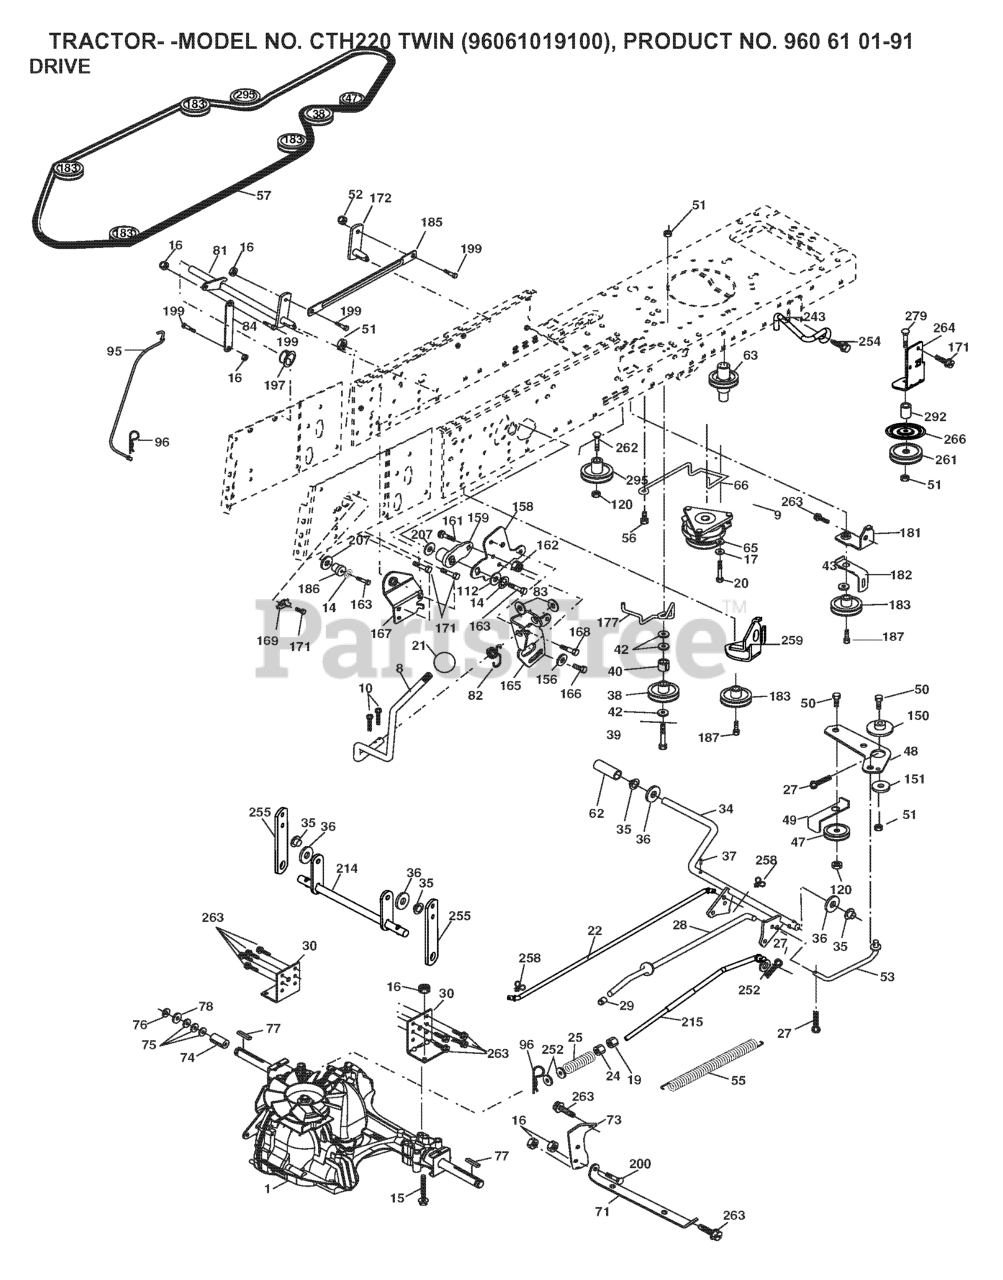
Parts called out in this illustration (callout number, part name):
8	ROD SHIFT FENDER ADJUST LT
9	CLUTCH.ELECTRIC.OGURA.EURO.
10	PIN COTTER
14	LOCKWASHER
15	BOLT HEX 5/16-18 GR 5
16	NUT.71038.31-18.HEX.NYLOCK
19	NUT
20	BOLT HEX 7/16-20X4-1/4"
21	KNOB.DUCKHEAD.1/2
22	ROD
24	NUT
25	SPRING BRAKE ROD
27	COTTER PIN
28	ROD, PARKING BRAKE
29	CAP
30	BRKT, TRNSXLE MNT 20"
34	SHAFT, FOOT PEDAL
35	BEARING.NYLON
37	DRIVE PIN
38	PULLEY.FLAT
42	WASHER
47	IDLER PULLEY
48	BELLCRANK, CLUTCH
49	RETAIN BELT
50	BOLT.3/8-16X1.50
52	LOCKNUT
53	LINK.CLUTCH.7.66.2005
55	SPRING, RETURN LT
56	SCREW.3/8-16
57	V-BELT 113"
62	PEDAL COVER T
63	PULLEY.ENGINE.CVX.LT
65	LOCKWASHER
66	KEEPER BELT ENGINE
71	STRAP TORQUE LH HYDRO
73	STRAP TORQUE RH HYDRO
74	SPACER AXLE
77	SQUARE KEY
81	ASM.CROSS.SHAFT.REAR.CRD.0510
82	SHIFT SPRING
83	WASHER
84	LINK.PNT.TRANSAXLE.0510.CRD
95	LINK
96	RETAINER M
120	NUT LOCK FLG 3/8-16 UNC
150	BUSHING.BELLCRANK.GRD.DR
151	WASHER 12/32X2X10GA
156	WASHER.SRRTD.5/16
158	BRACKET
159	RB HUB.SHIFT
161	BOLT
162	NUT.CROWNLOCK.1/4
165	RP BRACKET
166	CAPSCREW.HXHD.FLG.5/16-18X.625
167	BRACKET.SUPT.SHIFT.CRD
168	BOLT.SHOULDER.5/16-18X
169	PLATE.FASTENING.CROSS.SHAFT
172	LINK
181	BRACKET
182	BELT GUIDE
183	PULLEY.V-IDLER.GRND.DR
185	LINK
186	HUB.TAPERED.ROUND.CRD
187	BOLT.5/16-18X1.25
197	NYLINER SNAP 5/8" ID
199	BOLT SHOULDER 5/16-18 UNC
207	WASHER NYL
214	LEVER
215	ROD
243	BRACKET, ANTI-ROTATION
252	WASHER
254	SCREW 3/8-16X1
255	SHAFT
258	CLIP RETAINER
259	BRACKET
261	FLAT IDLER PULLEY
263	SCREW, 3/8-16X3/4
266	PROTECTOR
268	GUARD MUFFLER
275	WASHER
292	SPACER
295	PULLEY IDLER COMPOSITE
